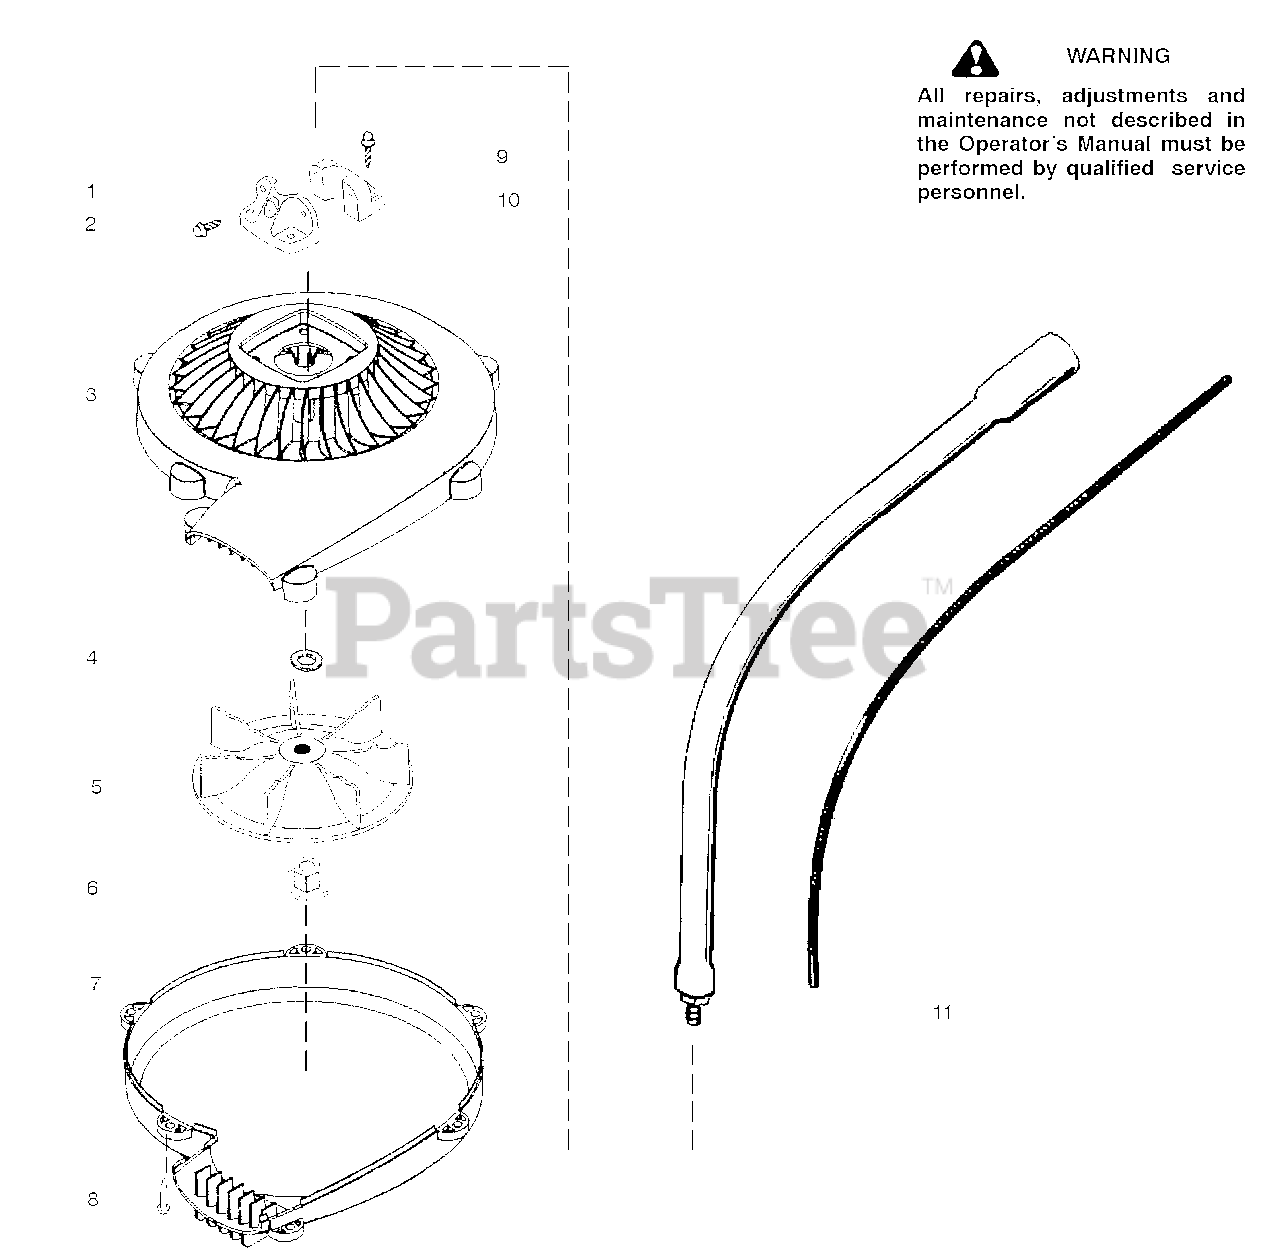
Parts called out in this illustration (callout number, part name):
3	Hsg.-Blower (upper)
6	Arbor-Impeller
7	Hsg.-Blower (lower)
11	Kit-Lower Driveshaft
